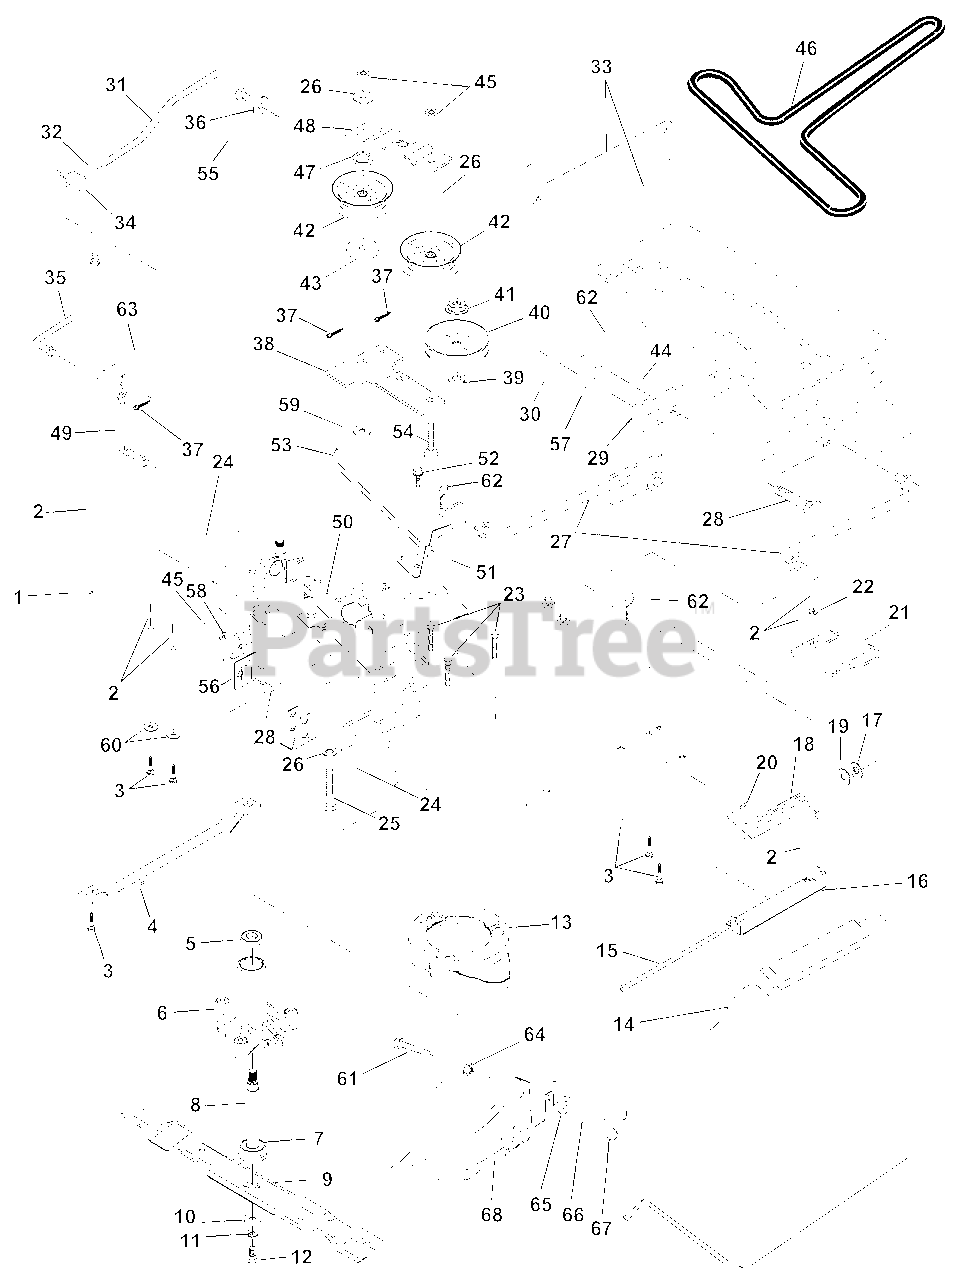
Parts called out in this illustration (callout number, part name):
1	Mower Deck Assembly
2	Nut, Crownlock 5/16-18
3	Bolt, Carriage 5/16-18 x 3/4
4	Runner, L.H.
6	Housing, Mandrel
8	Shaft and Bearing Assembly, Mandrel
10	Washer, Hardened
11	Washer, Lock 3/8
12	Bolt, Hex 3/8-24 x 1-1/4 Grade 8
13	Stripper, Mower, Vented
14	Shield, Deflector
15	Rod, Hinge
16	Bracket Assembly, Deflector
18	Spring, Deflector
19	Washer 11/32 x 5/8 x 16 Gauge
20	Cap, Sleeve
21	Runner, R.H.
22	Washer 11/32 x 3/4 x 16 Gauge
23	Screw Thdrol Hex Head Zinc MWR
24	Retainer, Spring
25	Bolt Hex 3/8-16 x 2-1/4
26	Washer 13/32 x 1 x 12 Gauge
27	Link Assembly, Front
28	Bolt RDHD SQNK 3/8 - 16 x 1
29	Plate Slide Link
30	Nut, Lock Hex w/washer 3/8 - 16
31	Clutch Rod, Primary
32	Nut, Hex, Jam 3/8-16
33	Arm, Suspension, Rear
34	Trunnion 3/8-16
35	Clutch Rod, Secondary
36	Washer 13/32 x 13/16 x 16 Gauge
37	Pin, Cotter 3/32 x 3/4
39	Washer .150 Thick
40	Pulley, Mandrel
41	Nut, Flangelock 9/16
42	Pulley, Flat Idler
43	Spacer, Retainer
44	Washer 13/32 x 1 x 12 Gauge
45	Nut, Crownlock 3/8-16
46	Belt
47	Spacer, Idler Arm
48	Stiffener, Idler Arm
49	Rod, Pivot
50	Rod, Brake, L.H.
51	Brake Assembly
52	Screw, Hex Washer Head, Thd., Roll. 5/16-18 x 3/4
53	Rod, Brake, R.H.
54	Bolt, Carriage 3/8-16 x 1-3/4 Grade 5
55	Spring, Retainer
56	Adjustment Plate, Rear Link, L.H.
57	Rondelle 13/32 x 1
58	Washer 13/32 x 3/4 x 12 Gauge
59	Washer Hardened
60	Washer 11/32 x 11/16 x 12 Gauge
61	Bolt 3/8-16 X 1-1/4
62	Retainer Spring
63	Retainer Spring
64	Nut Centerlock 3/8-16
65	Washer 13/32 X 1-1/4 X 16
66	Washer, Lock, Hvy
68	Cover Asm. Mulching 38
